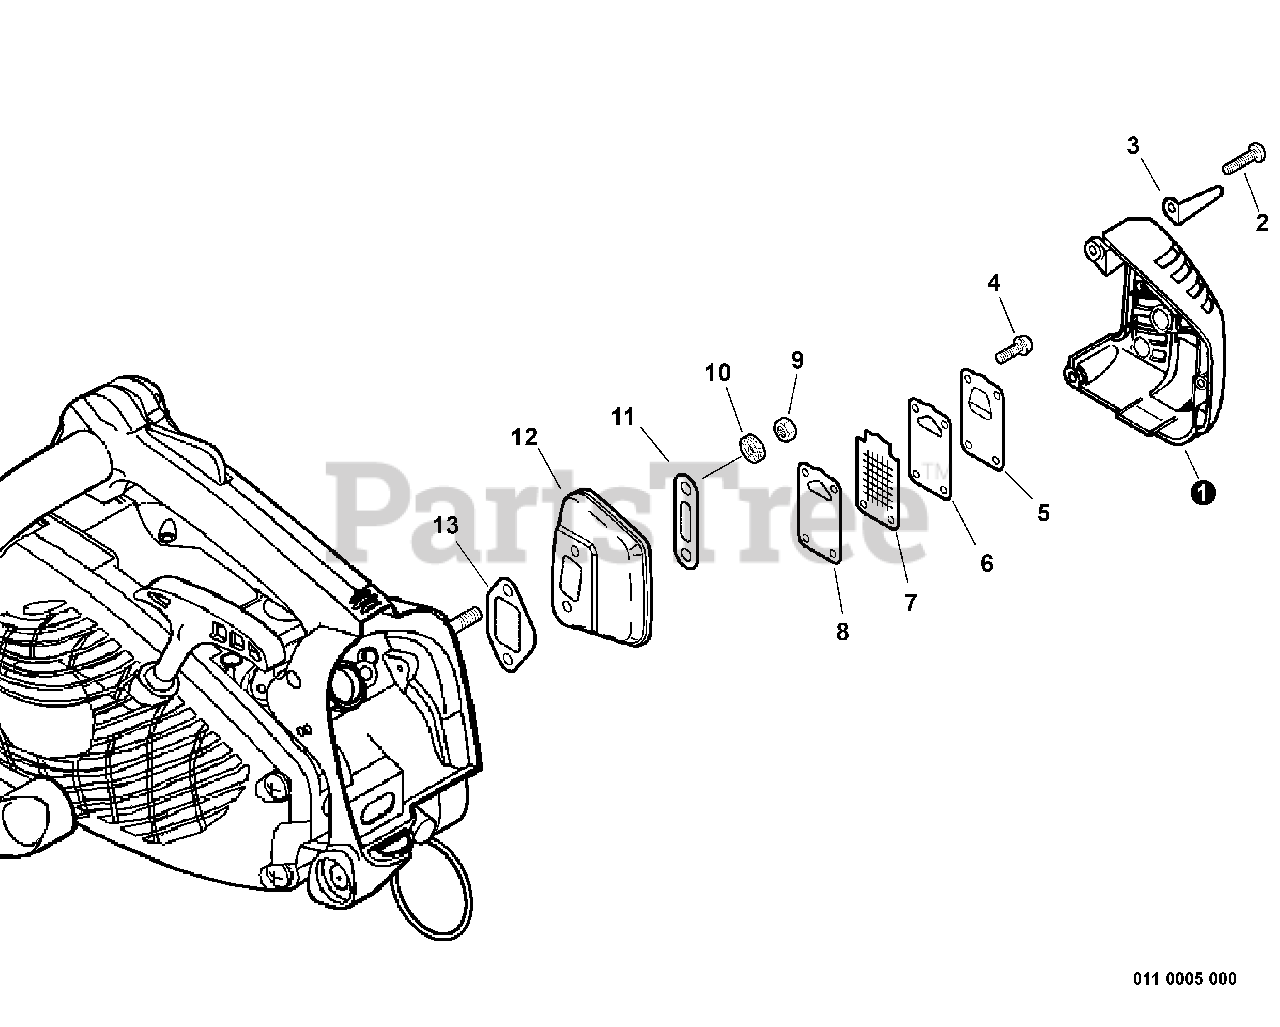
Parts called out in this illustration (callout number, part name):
1	COVER, EXHAUST - GRAY
1	COVER, EXHAUST - ORANGE
2	SCREW - 4X16
4	SCREW - 4X12
5	GUIDE, EXHAUST
6	GASKET, EXHAUST
7	SCREEN, SPARK ARRESTOR
8	GUIDE, EXHAUST
10	LOCKWASHER
12	MUFFLER
13	GASKET, EXHAUST
